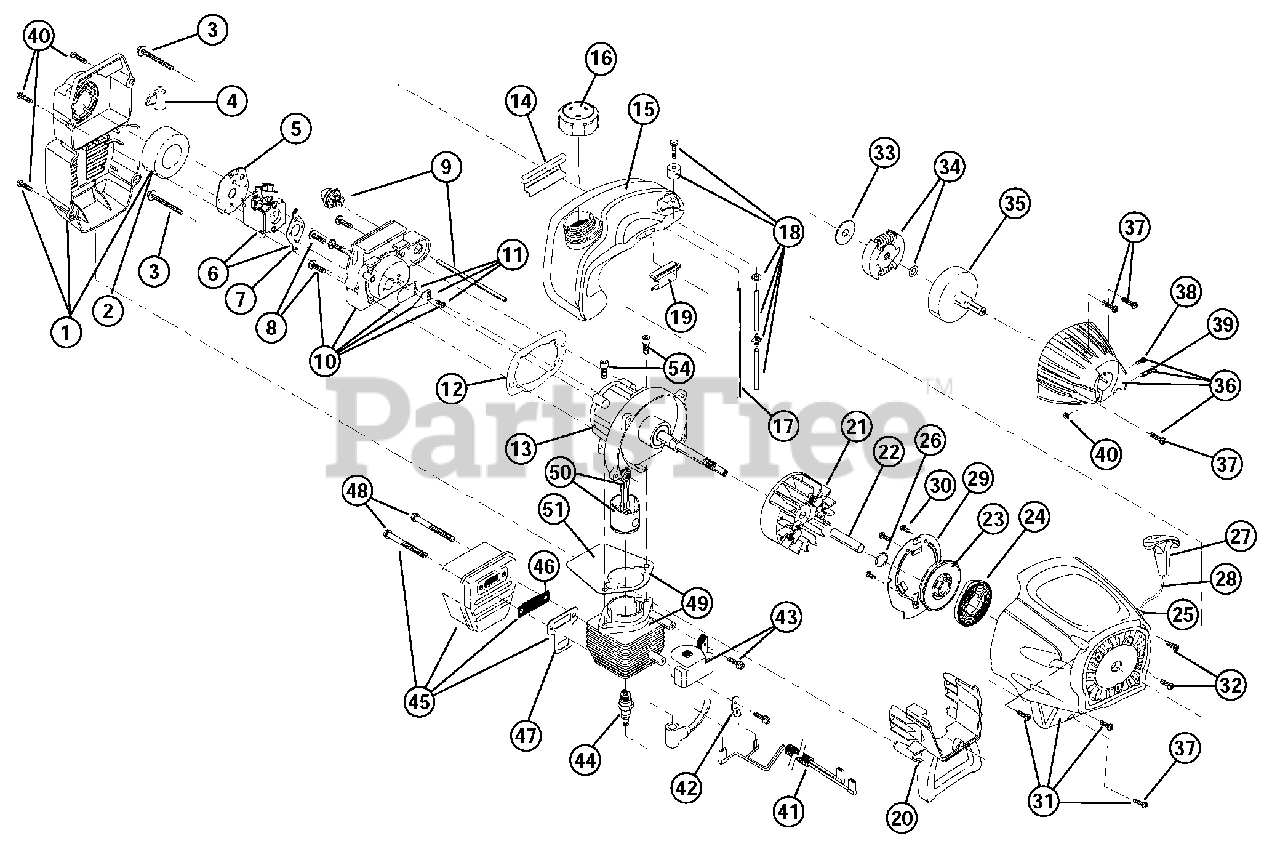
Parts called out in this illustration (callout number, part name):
1	Air Cleaner/Muffler Cover Assembly
2	Air Cleaner Filter
3	Carburetor Mounting Screws
4	Choke Extension
5	Choke Plate
6	Carburetor Assembly
7	Carburetor Gasket
8	Carb Mount Screw
9	Primer and Hose Assembly
10	Carb Mount Assembly
11	Reed Assembly
12	Carburetor Mount Gasket
13	Crank Case Service Assembly
14	Rear Mounting Pad
15	Fuel Tank Assembly
16	Fuel Cap Assembly
17	Fuel Return Line
18	Fuel Line Assembly
19	Front Mounting Pad
20	Shroud Extension and Stand
21	Flywheel Assembly
23	Recoil Pulley Assembly
24	Recoil Spring
25	Rope Guide
26	Pulley Retainer
27	Pull Handle
29	Pressure Plate Assembly
30	Plate Screw
31	Starter Housing Assembly
32	Housing Screw
33	Clutch Washer
34	Clutch Rotor Assembly
35	Clutch Drum Assembly
36	Clutch Cover Assembly
37	Cover Screw
38	Anti-Rotation Screw
39	Clamping Screw
40	Clamping Nut
41	Wire Leads and Sleeve
42	Ground Tab
43	Module Assembly
44	Spark Plug
45	Muffler Assembly
46	Spark Arrestor Screen
47	Exhaust Gasket
48	Muffler Mounting Bolt Assembly
49	Cylinder Assembly
50	Piston and Rod Assembly
51	Cylinder Gasket
52	Cylinder Bolt
